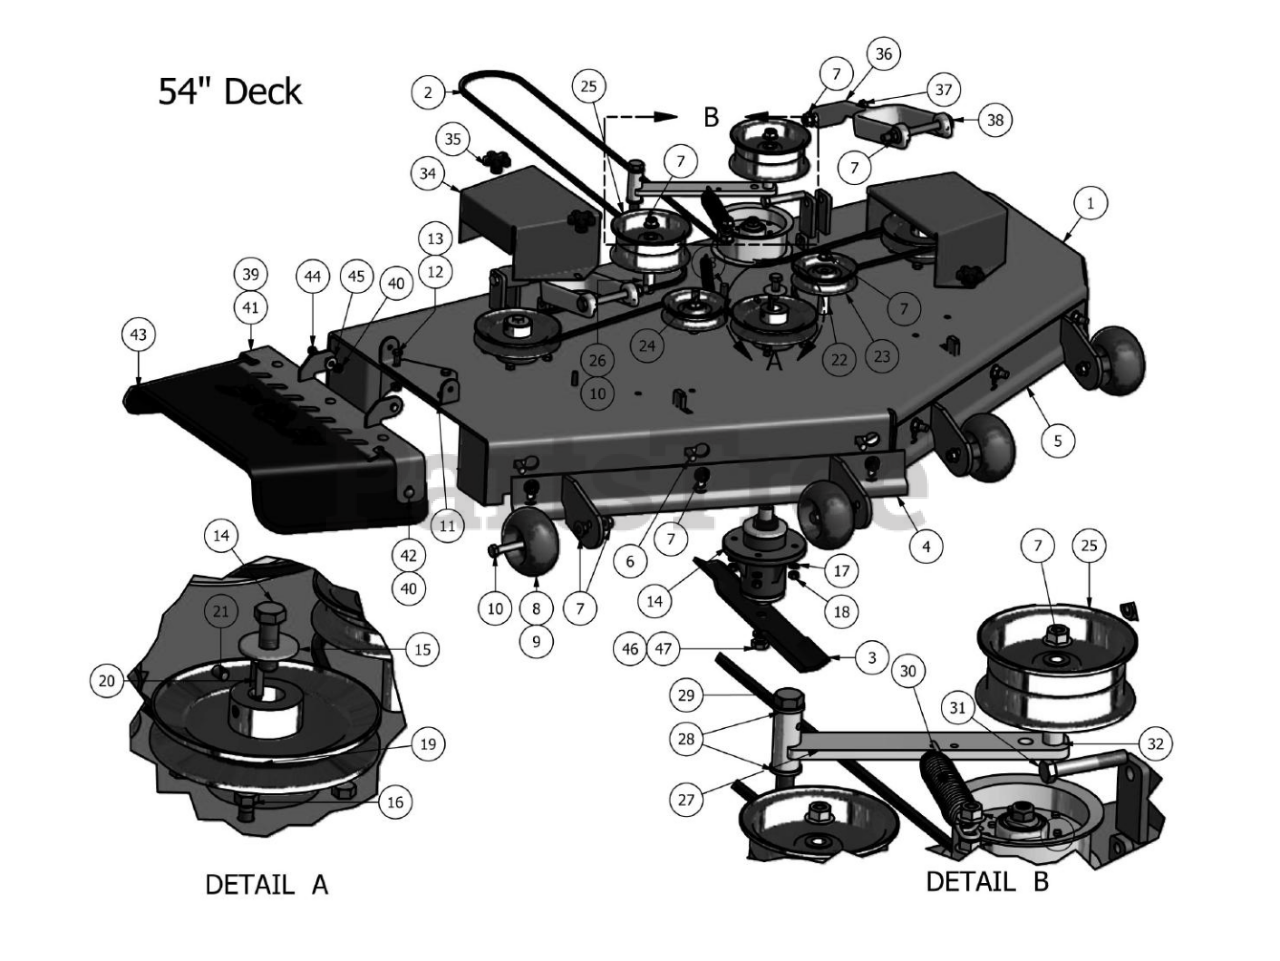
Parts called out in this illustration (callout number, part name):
1	54" Outlaw Deck
2	B165 Belt 54" Outlaw
3	54" Fusion Blade
4	54" Outlaw Adjustable deck Front (Right)
5	54" Outlaw Adjustable Deck Front (Left)
6	1/2 x 1-1/4 Carriage Bolt
7	1/2-13 Nylon Insert Flange Nut Zinc Orange
8	Anti-Scalp Rollers
9	Deck Wheel Assembly
10	1/2" x 4" Bolt (Grade 8)
11	Discharge Chute Hanger (deck mounted)
12	3/8" x 3/4" Hex Bolt
13	3/8" Flange Nut
14	1/2" x 1 1/2" Hex Bolt
15	Spring Blade Cupped Washer
16	3/8-16 x 1-1/4 GR 5 Hex Bolt Zinc
17	3/8" Lock Washer
18	3/8" Hex Nut
19	6 1/4" Drive Pulley
20	1/4" x 1" Key
21	3/8" Set Screw
22	Pulley Spacer
23	4 3/4" Idler Pulley
24	1/2 x 3-1/2 Flange Bolt - Grade 8
25	5 3/4" Deck Idler Pulley
26	1 3/4" Pulley Spacer
27	Deck Idler Bracket
28	.635 ID Plastic Washer
29	5/8" x 4" Hex Bolt
30	Deck Idler Spring
31	1/2" x 3" Hex Bolt
32	3/4 OD x 1/2 ID x 3\4 Length
33	1/2 x 2" Carriage Bolt
34	Pulley Cover
35	5/16" Knob
36	Deck Arm Assembly
37	1/2 x 2-1/2 Hex Bolt
38	1/2" x 5 1/2" Bolt
39	Lower Hanger
40	5/16-18 Nylon Insert Flange Nut Zinc Orange
41	Discharge Chute Upper Hanger Plate
42	5/16" x 1 1/4" Carriage Bolt
43	Rubber Discharge Chute (Rubber Only)
44	5/16-18 x 1 Grade 5 Hex bolt Zinc
45	.360ID Plastic Washer
46	5/8" Lock Washer
47	5/8" x 1 1/2" Grade 8 Bolt
